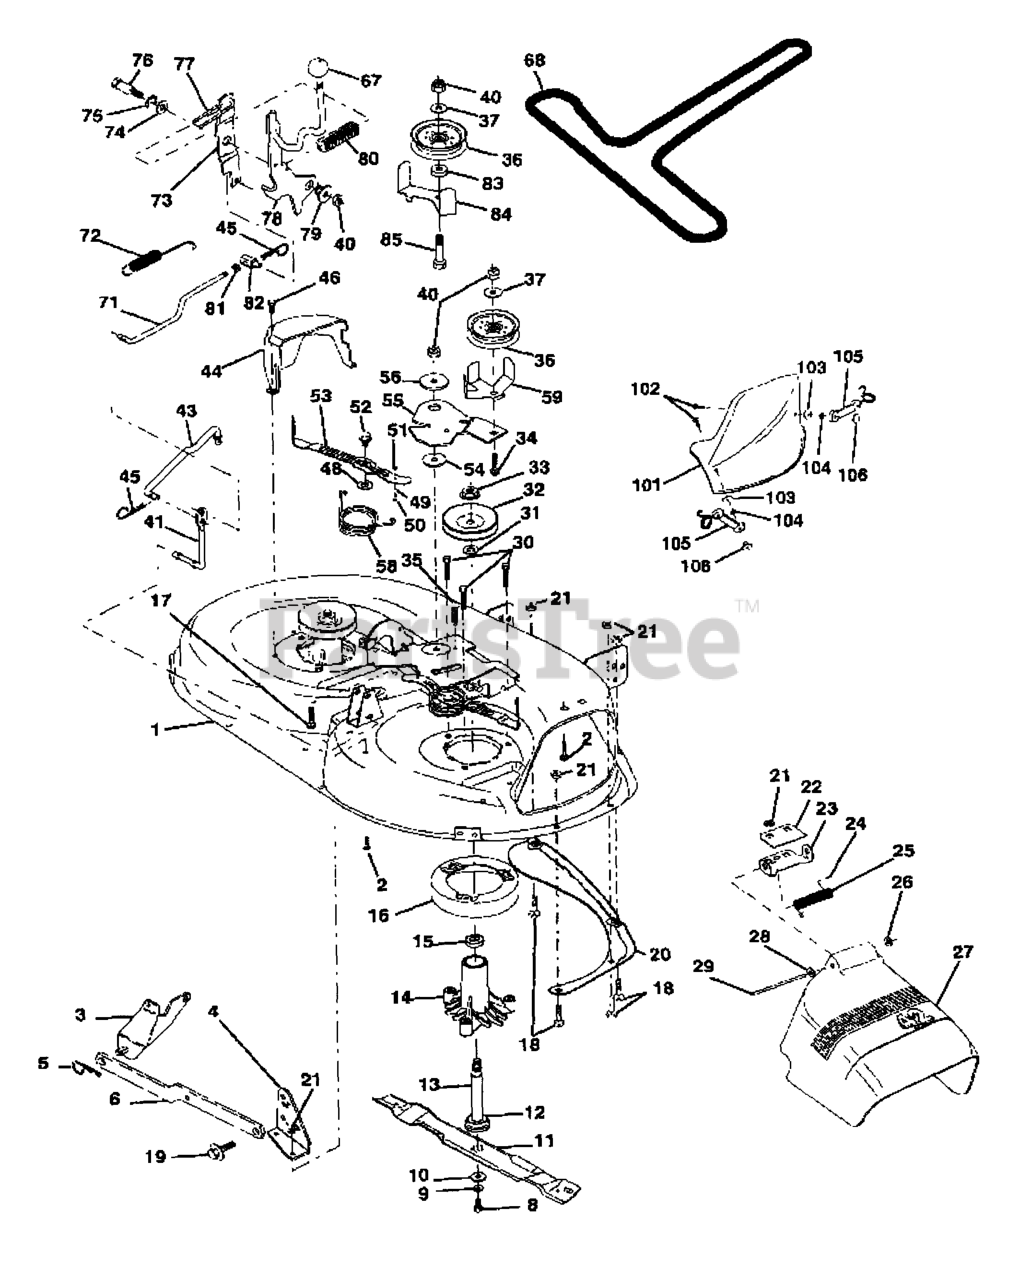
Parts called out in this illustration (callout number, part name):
1	DECK 42"
2	RP BOLT 5/16-18 X3/4 ZN/YEL GR
3	BRKT ASM SWAY BAR
4	BRKT DECK SW BAR
5	RETAINER-SPRNG RB
6	REAR SUSP ARM
8	BLADE BOLT
9	LOCKWASHER
10	WASHER.BLADE
11	BLADE.42".MULCH
12	BEARING.BALL.#6204.(MANDREL)
13	SHAFT ASM VENT
14	HOUSING.MANDREL.VENTED (MACHD)
16	STRIPPER
17	BOLT
18	BOLT
19	BOLT SHD 5/16-18
20	BAFFLE
21	LOCKNUT
22	STIFFENER BRACKET
23	DEFLECTOR BRACKET
24	CAP-SLEEVE LT
25	SPRING TORSION
26	NUT PUSH M
27	SHIELD.DEFLECTOR.MOWER.42".BLK
28	Washer 11/32 X 5/8 X 16 Ga
29	ROD.HINGE
30	SCREW
31	WASHER
32	MANDREL PULLEY
33	NUT
35	FASTENER.XMAS.TREE
36	FLAT IDLER PULLEY
37	WASHER
43	CLUTCH ROD
44	GUARD MANDREL LH BLACK
45	RETAINER M
46	SCREW.1/4-20X5/8
49	CAM FOLLOWER
52	BOLT.SHOULDER.5/16-18
53	ARM
54	HARDENED WASHER
55	IDLER ARM
56	SPACER RETAINER
59	GUARD, BELT
67	KNOB T (1/2-HOLE)
68	V-BELT TRIPATH
71	CLUTCH ROD
72	RETURN SPRING
73	ARM CLUTCH SECONDARY
77	KEEPER SPRING
78	CLUTCH ARM
79	BUSHING.FLANGE.E-RING.GROOVE
80	SPRING
81	NUT
82	TRUNNION.ADJUSTABLE.3/8-16
84	KEEPER BELT
85	BOLT
101	COVER MULCH 42"
102	SCREW
104	LOCKWASHER #10
105	LATCH ASSEMBLY
106	WELDNUT
